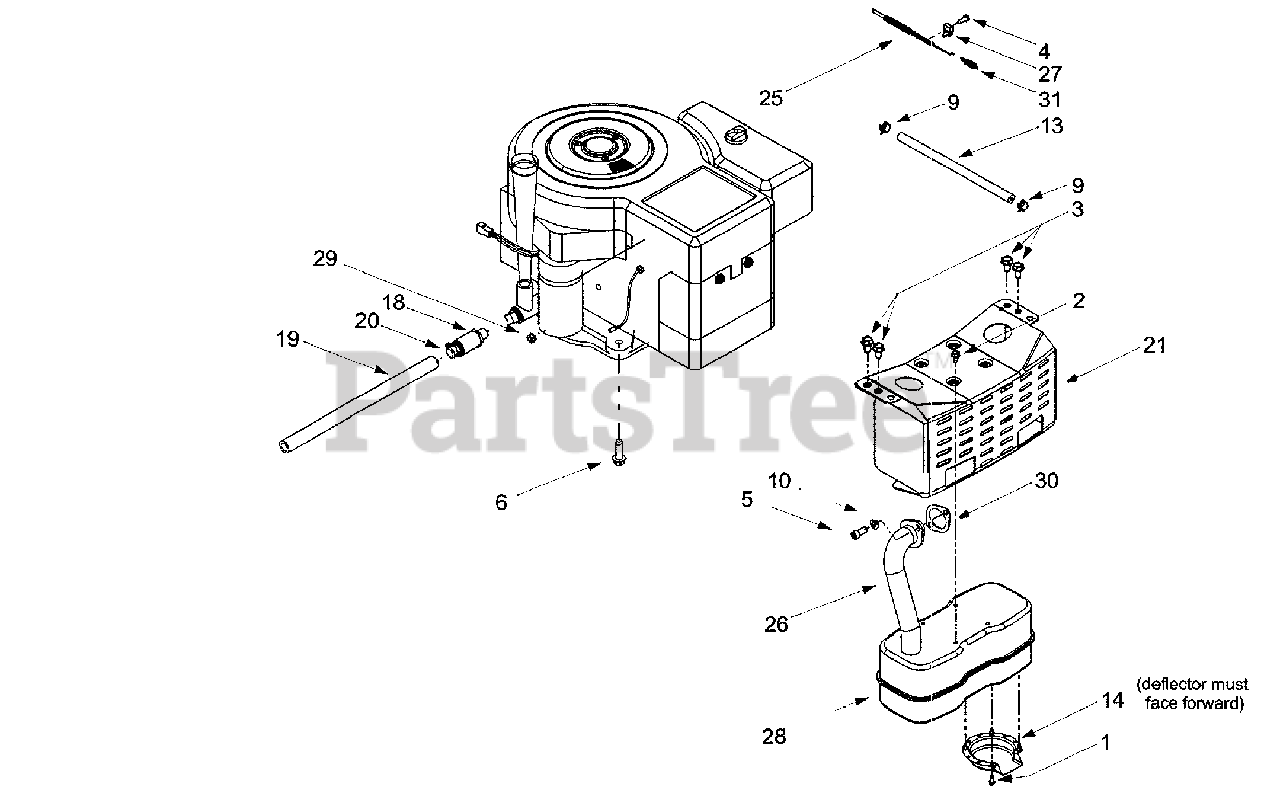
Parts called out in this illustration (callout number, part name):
1	Self-tapping Screw, #8-18 x .5
2	Self-tapping Screw, 1/4-20 x.5
3	Self-tapping Screw, 5/16-18 x .625
4	Screw, #10-32 x .625
5	Socket Cap Screw, 5/16-18 x .625
6	Self-tapping Screw, 3/8-16 x 1.25
9	Hose Clamp
10	Lock Washer, 5/16
13	Fuel Line Hose
14	Muffler Deflector
18	Oil Drain Valve
19	Oil Drain Hose
20	Oil Drain Cap
25	Throttle/Choke Cable
26	Exhaust Pipe
27	Casing Clamp
28	Muffler, Single Inlet
29	Hex Sems Nut, 1/4-20
30	Exhaust Gasket
31	Extension Spring, .275 x 1.25
